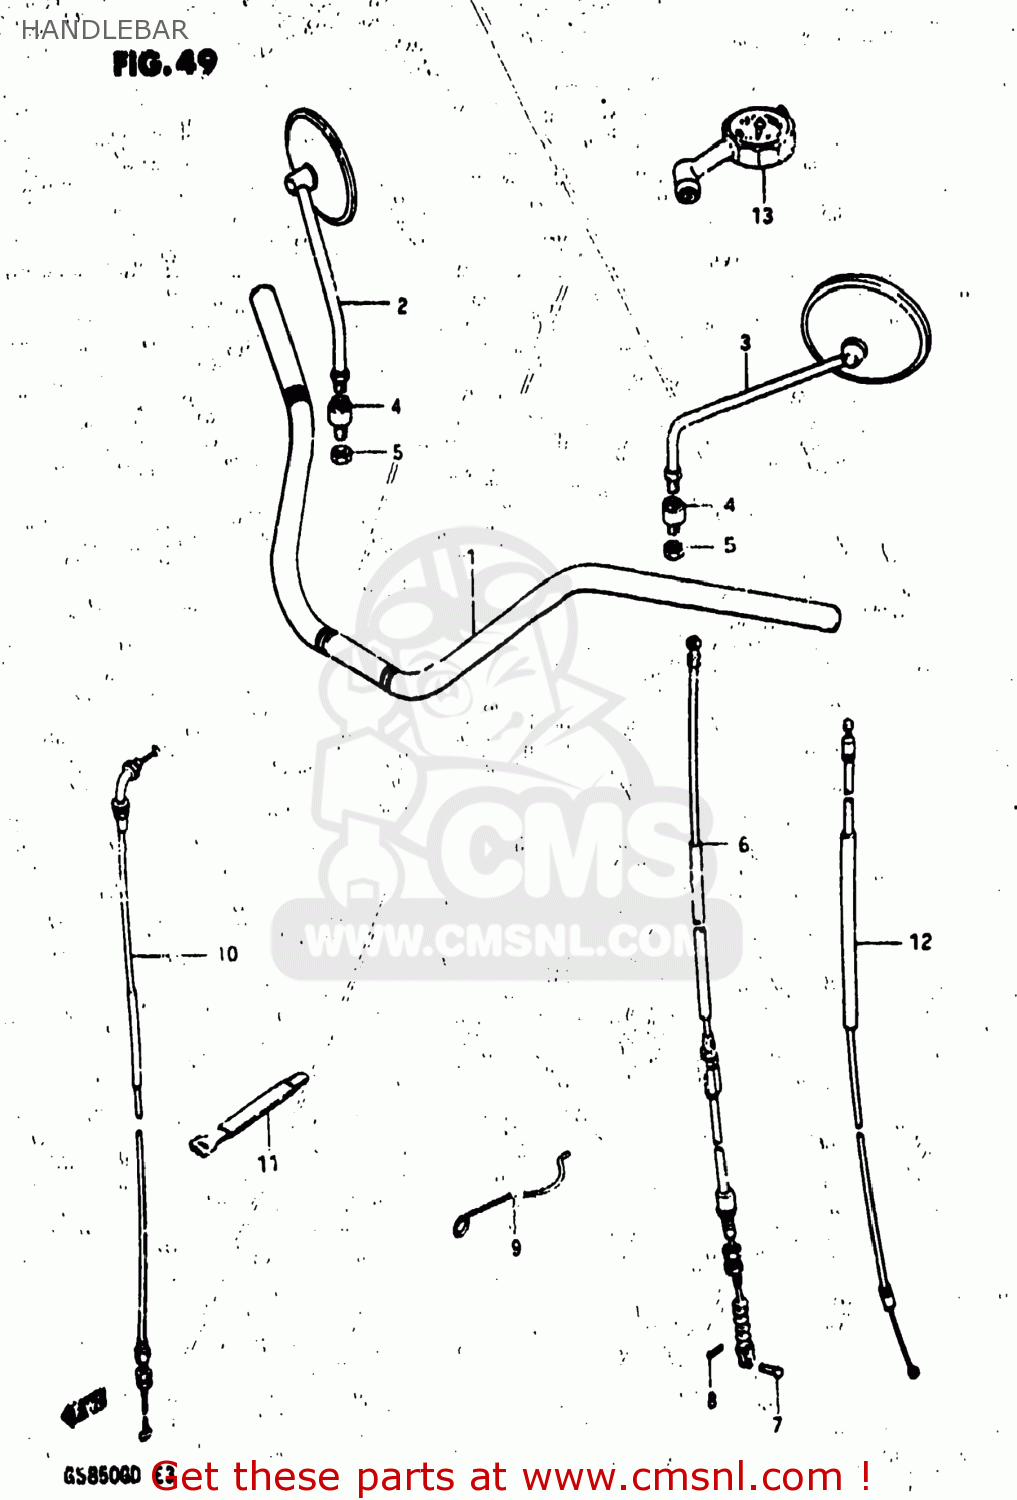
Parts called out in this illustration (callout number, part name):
1	HANDLEBAR
2	MIRROR ASSEMBLY,RIGHT
3	MIRROR ASSEMBLY,LEFT
4	CUSHION,REAR VIEW MIRROR
5	NUT
6	CABLE ASSY,CLUTCH
7	PIN(L:15)
8	PIN
9	GUIDE,CABLE
10	CABLE ASSEMBLY,THROTTLE
11	CLAMP
12	CABLE,STARTER
13	GAUGE ASSY,AIR PRESSURE
